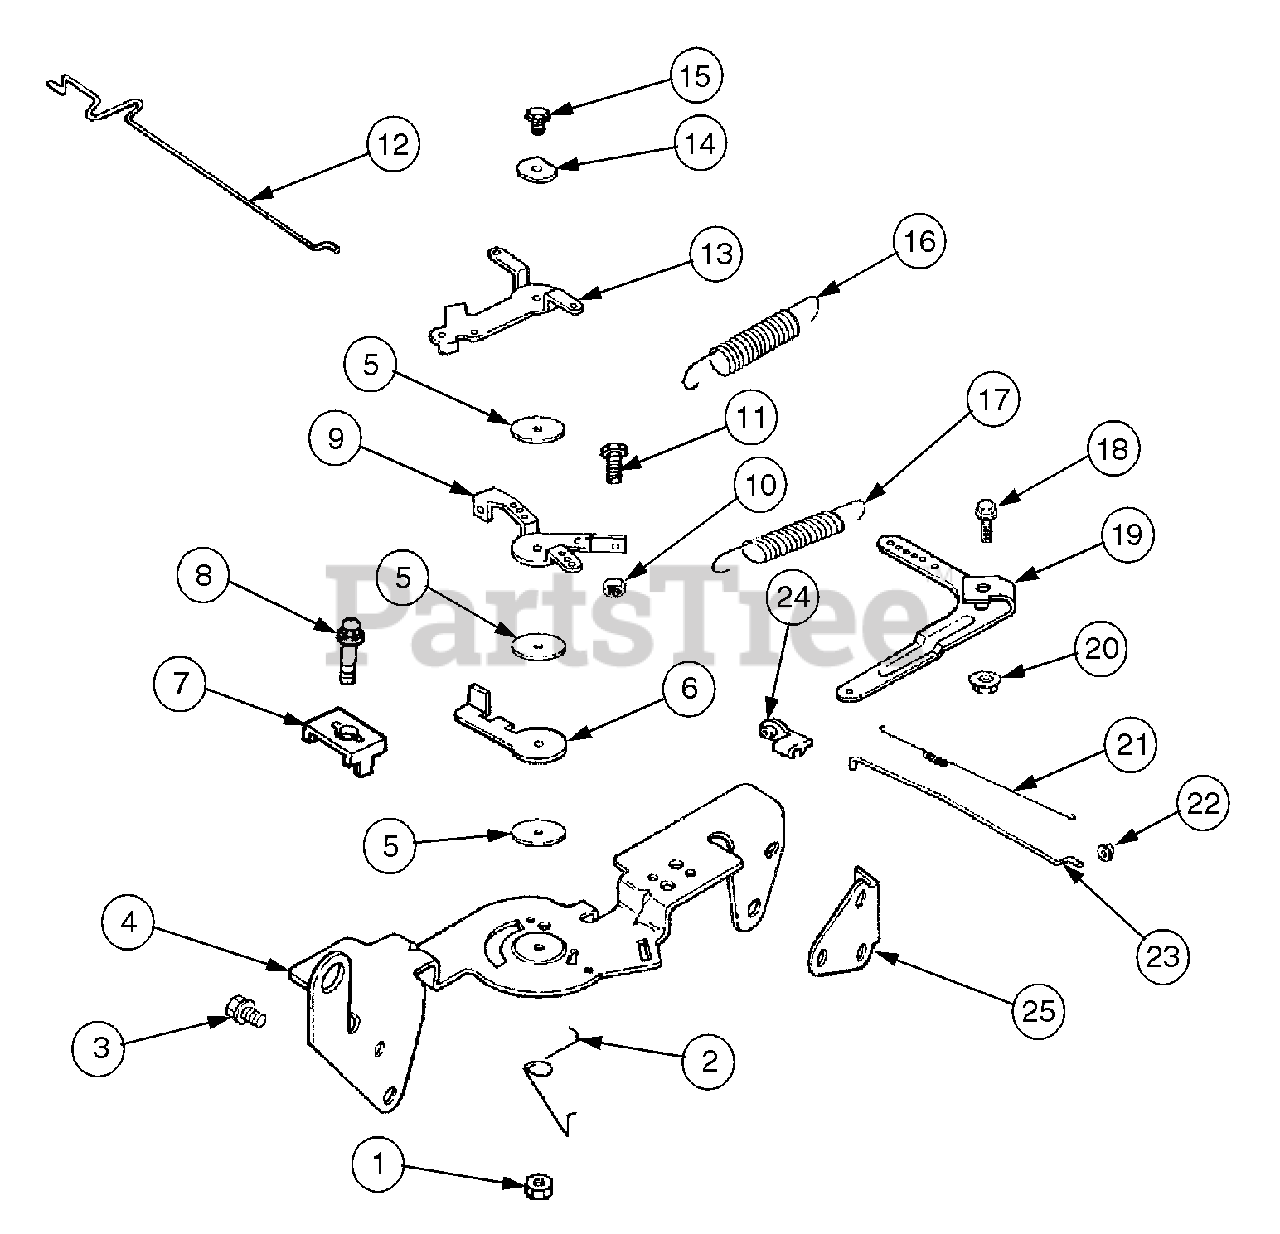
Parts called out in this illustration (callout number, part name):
1	Nut, Hex Lock M5 x 0.8
2	Spring, Choke Return
3	Screw, Hex Flange M6 x 1.0 x 16
4	Bracket, Control
5	Washer, Plain 5.5mm
6	Lever, Throttle Actuator
7	Clamp, Cable
8	Screw, Hex Flange M5 x 0 8 x 16
9	Lever, Throttle Control
10	Nut, Hex M4 x 0.7
11	Screw, Hex Cap M4 x 0.7 x30
12	Linkage, Choke
13	Lever, Choke
14	Washer, Spring 1/4"
15	Screw, Hex Flange M5 x 0,.8 x 20
16	Spring, Throttle Limiter
17	Spring, Governor (6mm)
18	Screw, Hex Flange (6mm)
19	Lever, Governor (6mm)
20	Nut, Hex Flange M6 x 1.0
21	Spring, Linkage
22	Bushing, Linkage Retaining
23	Linkage, Throttle
24	Bushing, Linkage Retaining
25	Bracket, Support
